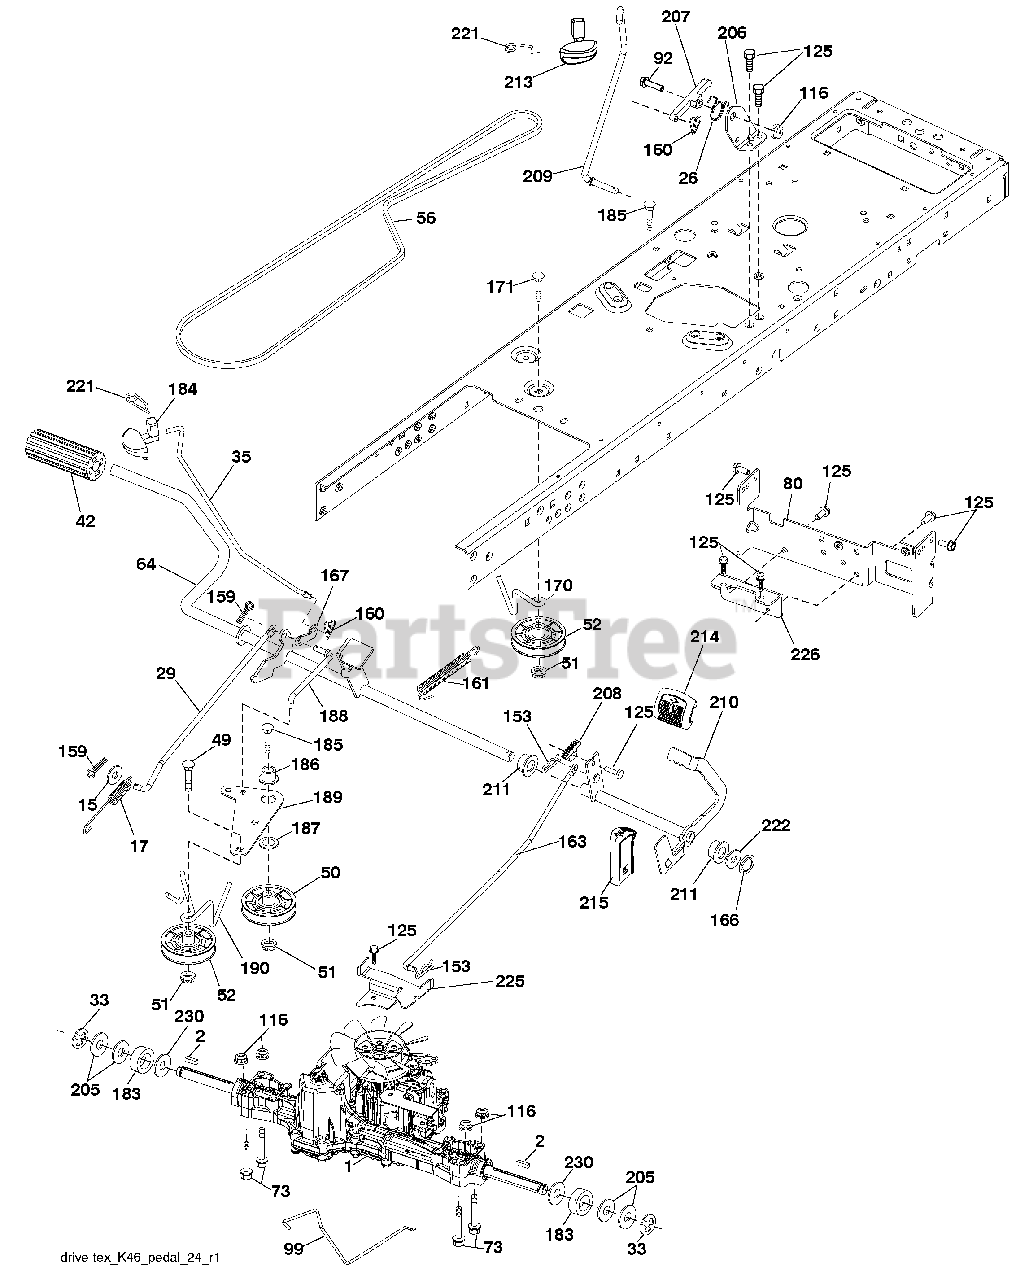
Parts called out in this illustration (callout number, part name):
2	Key
15	Washer 13/32 x 13/16 x 16 Ga.
17	Spring, Brake
26	Spring Return Cruise
29	Rod, Brake
33	Ring E
35	Rod, Brake, Park
42	Cover, Foot Pedal
49	Bolt
50	Pulley Idler Flat
51	Lock Nut 3/8-16
52	Idler V-Groove 910" Offset
56	V-Belt, Drive
64	Shaft Asm. Pedal Brake Control
73	Bolt Hex 5/16-18 x 3.75
80	Strap Torque
92	Bolt Fin Hex 5/16-18 unc x 1.25
99	Rod Spring Bypass
116	Nut Lock Hex Flange 5/16-18
125	Screw 5/16-18 x 3/4
153	Retainer Spring
159	Pin Cotter 1/8 x 3/4
160	Retainer Clip
161	Spring, Return, Clutch
163	Rod Pedal Control
166	Nut Push .625
167	Latch Brake Parking
170	Keeper Belt Centerspan
171	Bolt
183	Spacer Axle
184	Handle Parking Brake
185	Bolt
186	Spacer Retainer
187	Washer
188	Link Clutch Ground Drive
189	Bellcrank Ground Drive
190	Keeper Bellcrank Ground Drive
205	Washer 25/32 x 1-5/8 x 16 Ga.
206	Bracket Mount Latch Cruise
207	Latch Control Cruise
208	Gear Sector Control Cruise
209	Rod Control Cruise
210	Rockr Asm. Pdeal Control
211	Bearing Nylon
213	Knob control Cruise
214	Pad Pedal Forward
215	Pad Pedal Reverse
221	Retainer Spring Clip Handle
222	Washer 21/32 x 1-1/4 10 Ga.
225	Keeper Belt Transaxle
226	Bracket Mount Torque
230	Washer Harden .793 x 1.637 x 060
